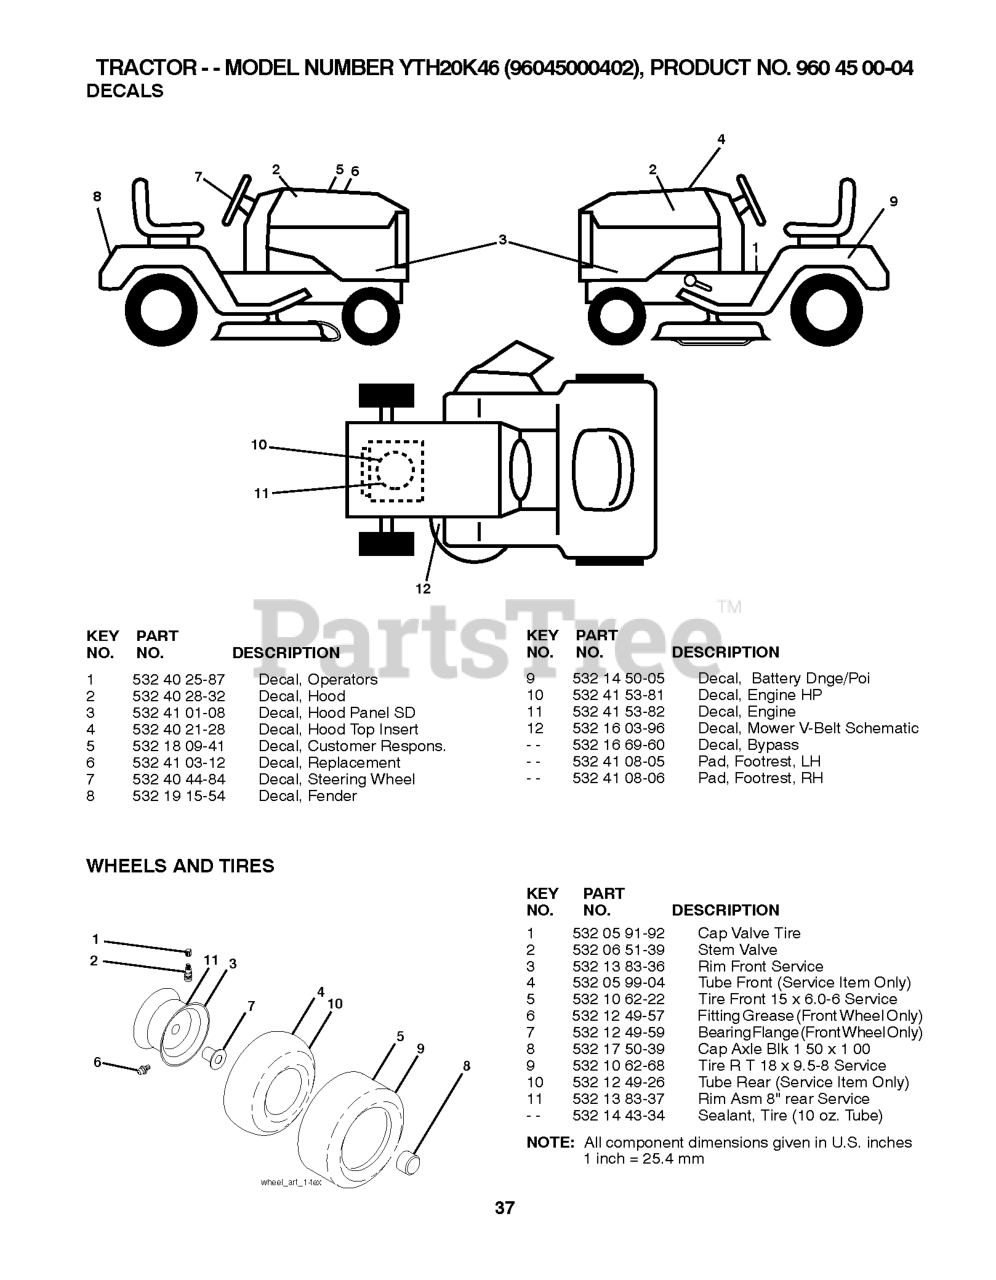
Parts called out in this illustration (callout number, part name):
2	VALVE STEM LT
3	RIM ASM 6" FRONT SILVER
4	TUBE.5.3/4.5/6
5	TIRE HEAVY DUTY
6	FITTING LT
7	BEARING T
8	CAP, AXLE BLK
9	TIRE HEAVY DUTY
10	TUBE
11	RIM ASM 8" REAR SILVER
